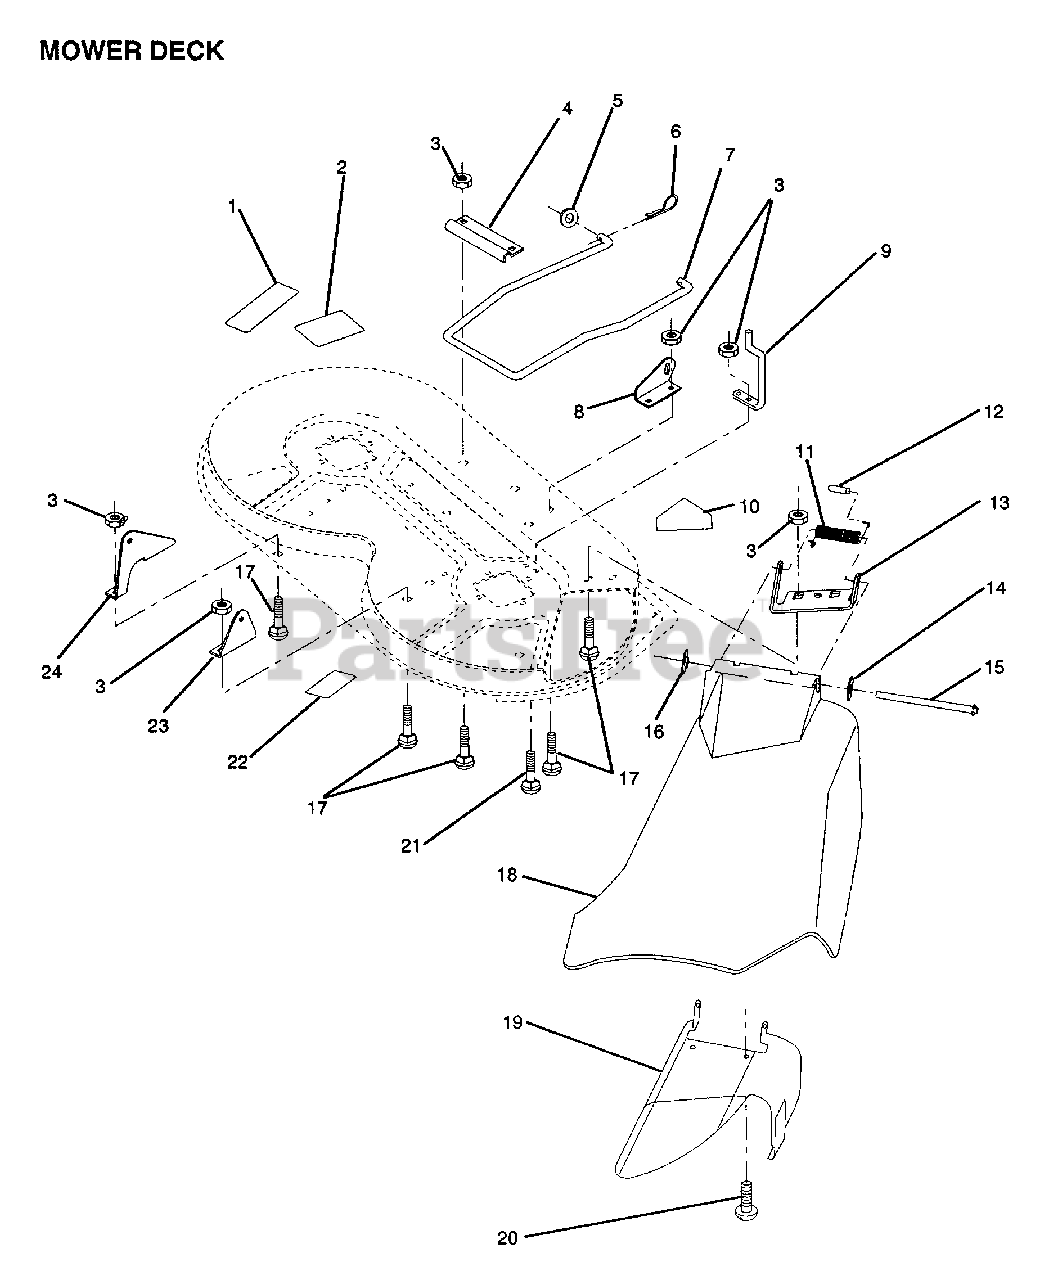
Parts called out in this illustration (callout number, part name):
1	DECAL YT
2	DECAL.LT
4	"BRKT,STAB LINK"
6	RETAINER.SPRING
7	STABILIZER MOWER
8	"BRKT,FRT LIFT RH"
9	"GUIDE,FRT MAN RH"
10	DECAL WARNING
11	SPRING TORSION
12	CAP-SLEEVE LT
14	WASHER
15	HINGE ROD
16	NUT PUSH M
17	BOLT
19	DEFL SUPT ASS'Y
20	SCREW PAN HD
21	BOLT
22	DECAL WARNING
23	"BRKT,REAR LIFT RH"
24	"BRKT,REAR LIFT LH"
